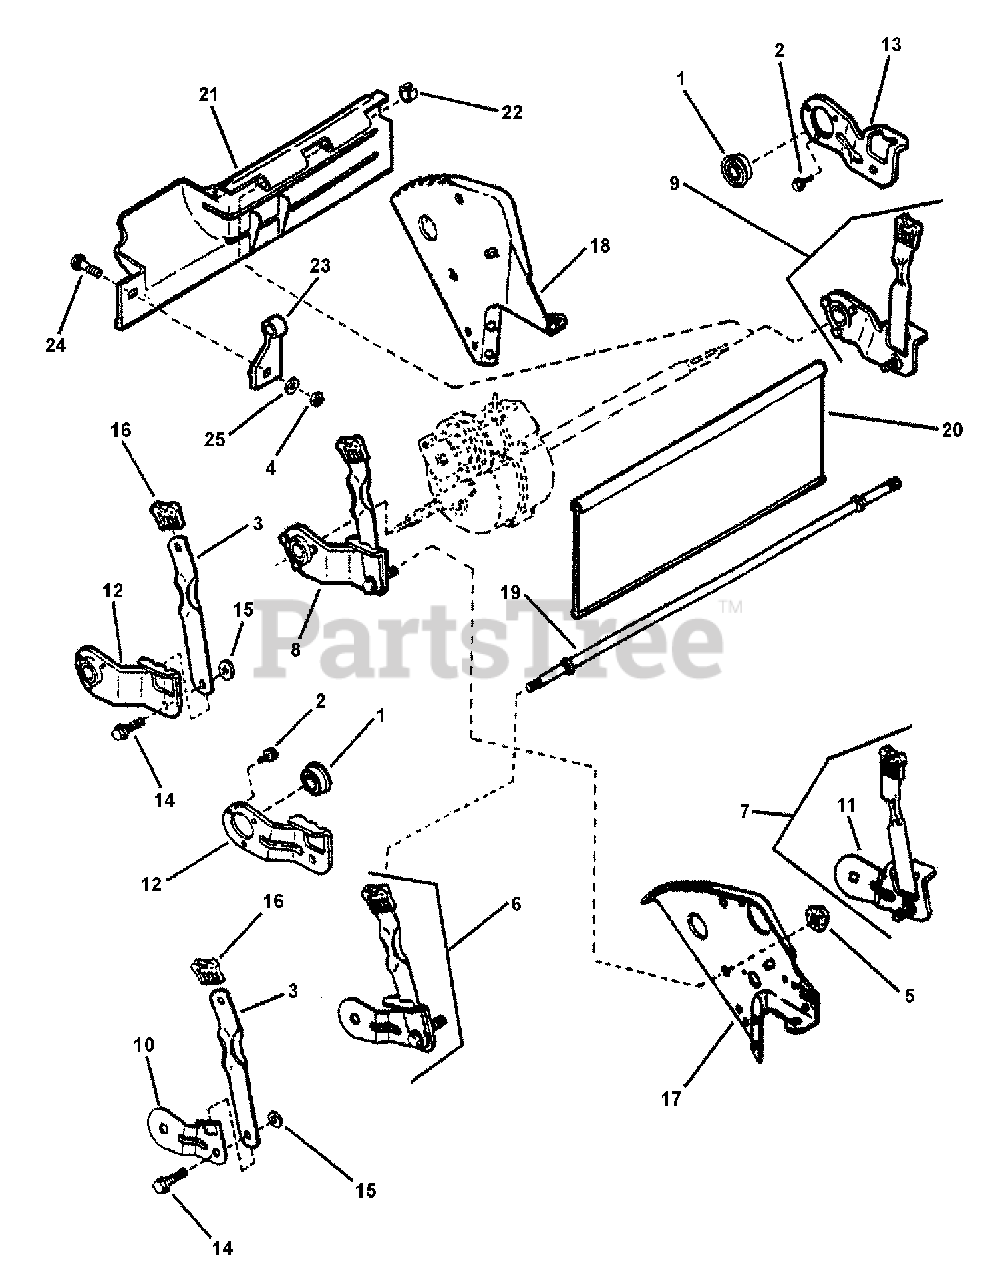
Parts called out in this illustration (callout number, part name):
1	BALL BEARING, 9/16" I.D.
1	BALL BEARING, 9/16" I.D. (Commercial)
2	SCREW, #10-32 x 3/8" Hex Washer Self-Tap
3	LATCH, Height Adjusting (Long)
4	NUT, 1/4-20 Hex
5	NUT, 5/16-18 Hex Flange Lock, GR5
6	ASSEMBLY, Wheel Arm, Right Rear (Round hole)
7	ASSEMBLY, Wheel Arm, Left Rear (Square hole)
8	ASSEMBLY, Wheel Arm (Right Rear)
8	ASSEMBLY, Wheel Arm, Right Rear
9	ASSEMBLY, Wheel Arm (Left Rear)
9	ASSEMBLY, Wheel Arm, Left Rear
10	ARM, Round Axle End, Right Rear (Round hole)
11	ARM, Square Axle End, Left Rear (Square hole)
12	ARM, Wheel, Right Rear
13	ARM, Wheel, Left Rear
14	BOLT, 5/16-18 x 1" Shoulder
15	RETAINER, 5/16" Bolt
16	GRIP, Latch
17	BRACKET, Right Rear Wheel
18	BRACKET, Left Rear Wheel
19	AXLE
20	GUARD, Rear Foot
21	GUARD, Rear Foot
22	RING, Split (Black)
23	SUPPORT, Foot Guard
24	BOLT, 1/4-20 x 1/2" Short Neck Carriage GR5
25	WASHER, 1/4" Internal Tooth Lock
